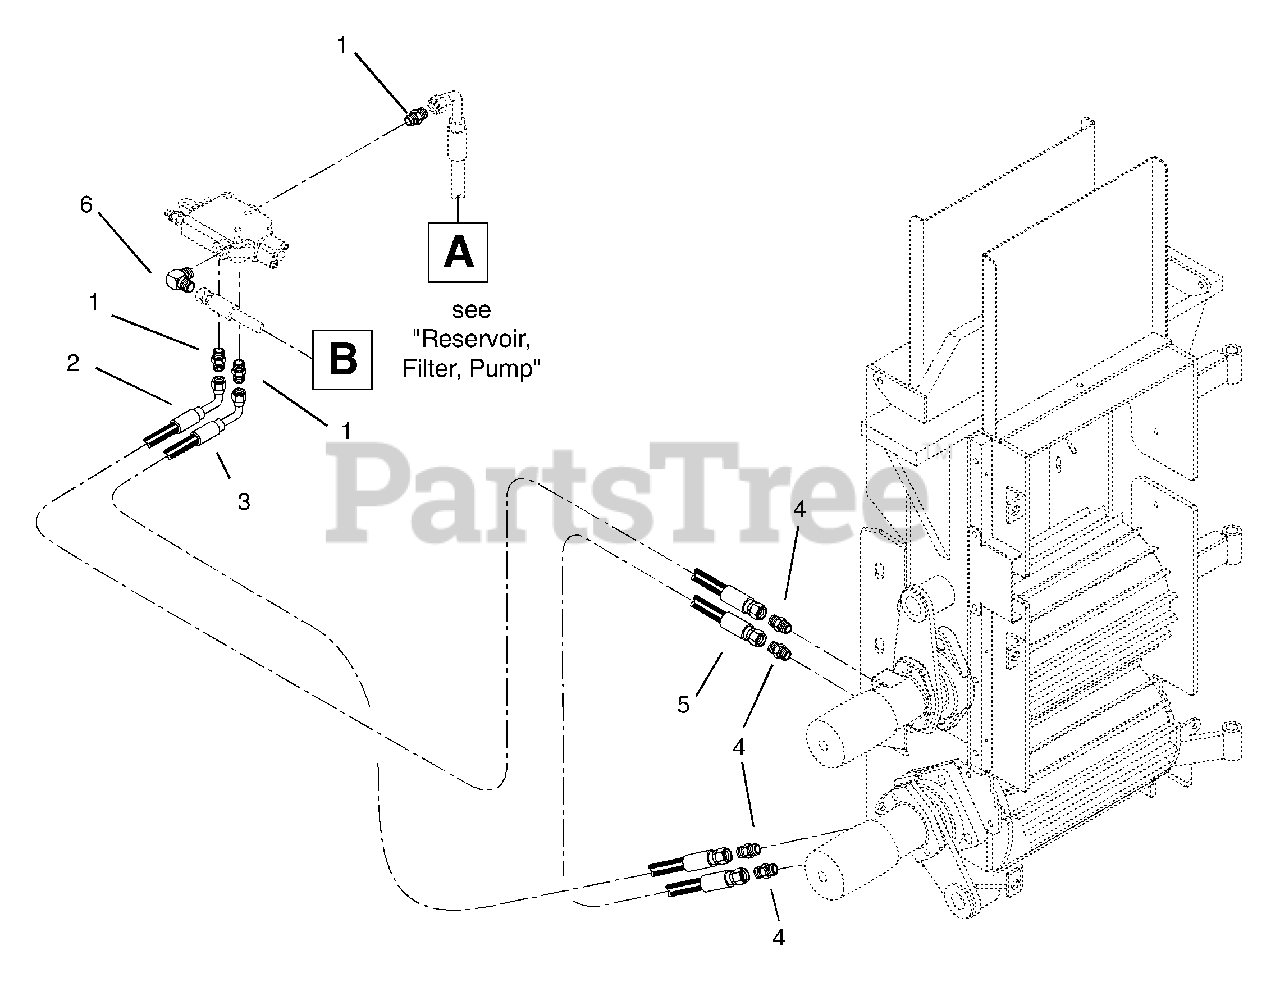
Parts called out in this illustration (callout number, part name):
1	Adapter-Hydraulic Straight 3/4 "O" to 3/4
2	Hose-Hydraulic 45' with Elbow
3	Hose-Hydraulic 30' with Elbow
4	Adapter-Hydraulic Straight 7/8 "O" to 3/4
5	Hose-Hydraulic 40'
6	Adapter-Hydraulic Elbow 3/4 "O" to 3/4
